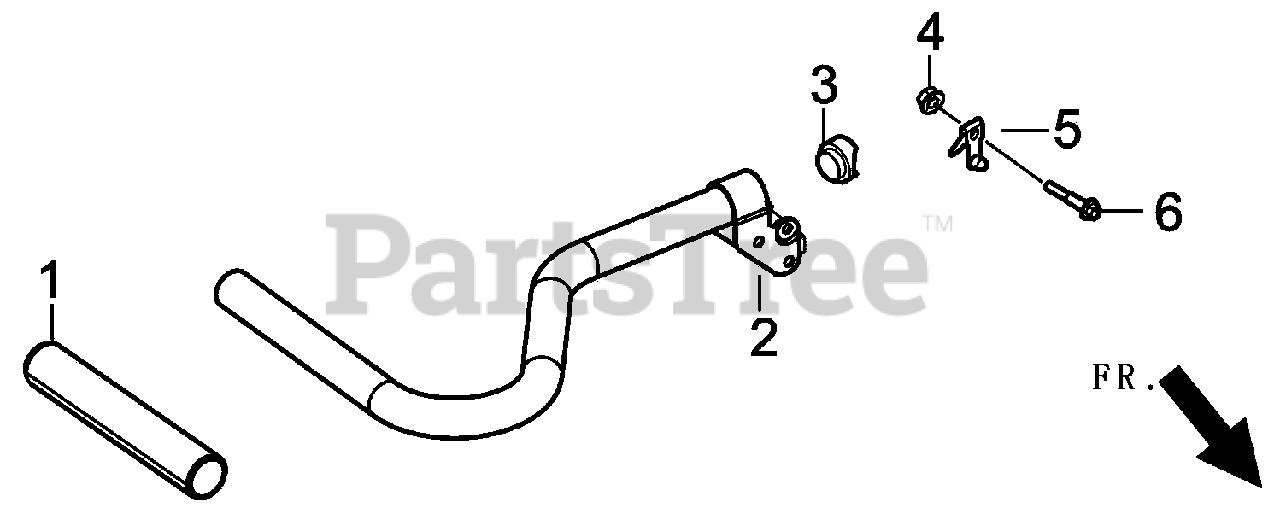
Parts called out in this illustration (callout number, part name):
1	HANDLE GRIP GP
2	TUBE, HANDLE
3	BUMPER HANDLE GP
